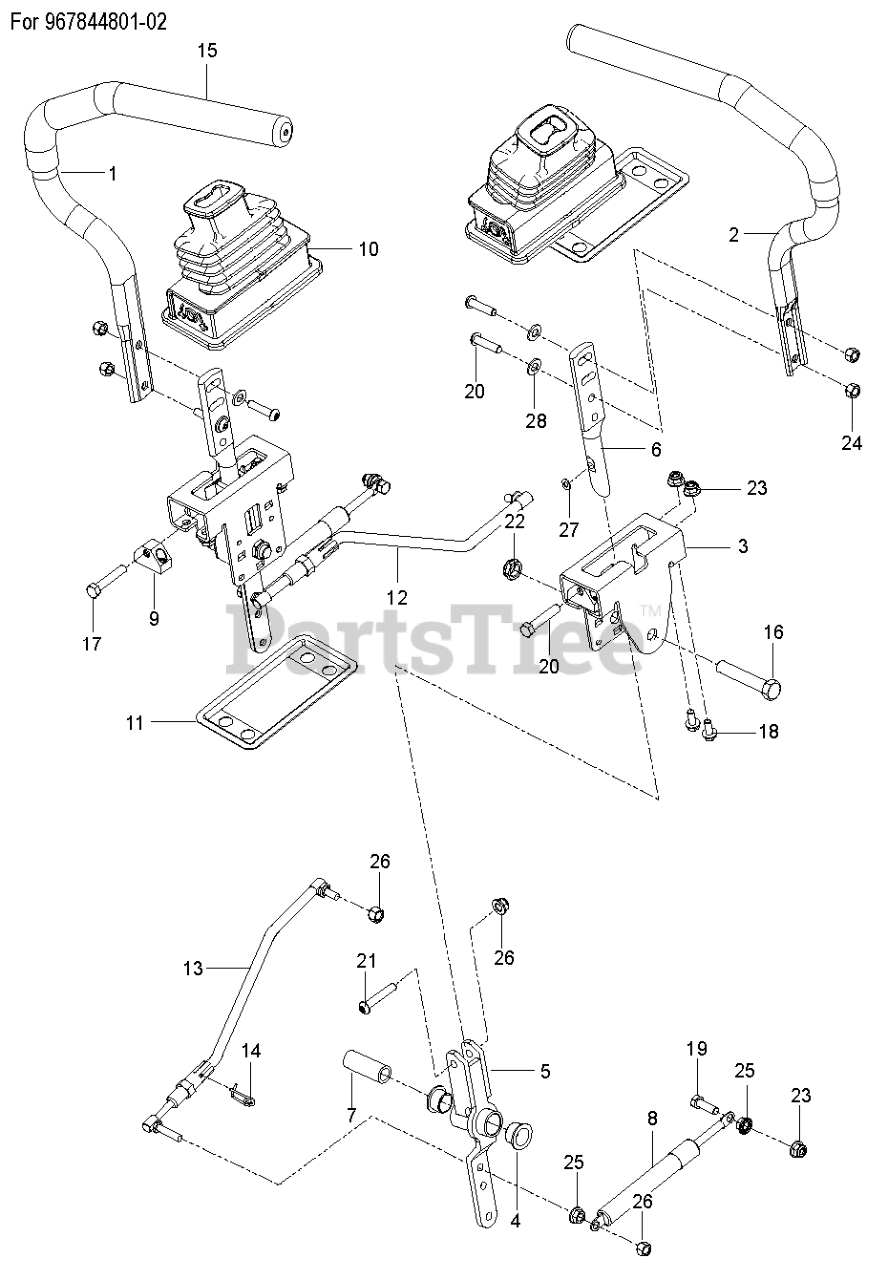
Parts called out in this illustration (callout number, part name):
1	TUBE.LEVER.CONTROL.ZTR.RT.428
1	TUBE RZ CONTROL LEVER RIGHT MS
2	TUBE.LEVER.CONTROL.ZTR.LT.428
3	BRACKET.CONTROLS.ZTR.X431
4	BEARING, FLANGE
5	LEVER CONTROL PIVOT
6	CONTROL.LEVER.HANDLE
7	SPACER.PIVOT.CONTROL
9	BLOCK TRACKING CONTROL ZTR
10	BOOT.STEERING.LEVER
11	CONTROL.BOOT.FLANGE.X431
12	ROD.ASM.RH.ADJUSTABLE
13	ROD.ASM.LH.ADJUSTABLE
14	RETAINER.CLIP.SPRING.S
15	PURCHASE THE COMPLETE LEVER
16	HCS 1/2-13 X 2-3/4 GD 5 ZD
17	SCREW.SHAKEPROOF.1.25.BLACK
18	HHFS 5/16-18 X 3/4
19	BOLT.5/16-18X1-1/4 FULL.THREAD
20	BUTTONHEAD.5/16-18X1.125.BLACK
21	SCREW.CAP.SOCKET.6PT.5/16-18
22	NUT 1/2-13 HEX JM NYL
23	5/16-18 NYLOC FLANGE NUT
24	NYLOCK.NUT.5/16-18 BLACK
25	NUT 5/16C WHIZ
26	NUT.71038.31-18.HEX.NYLOCK
27	WASHER.11/32ID.11/16OD.116THIC
28	WASHER
